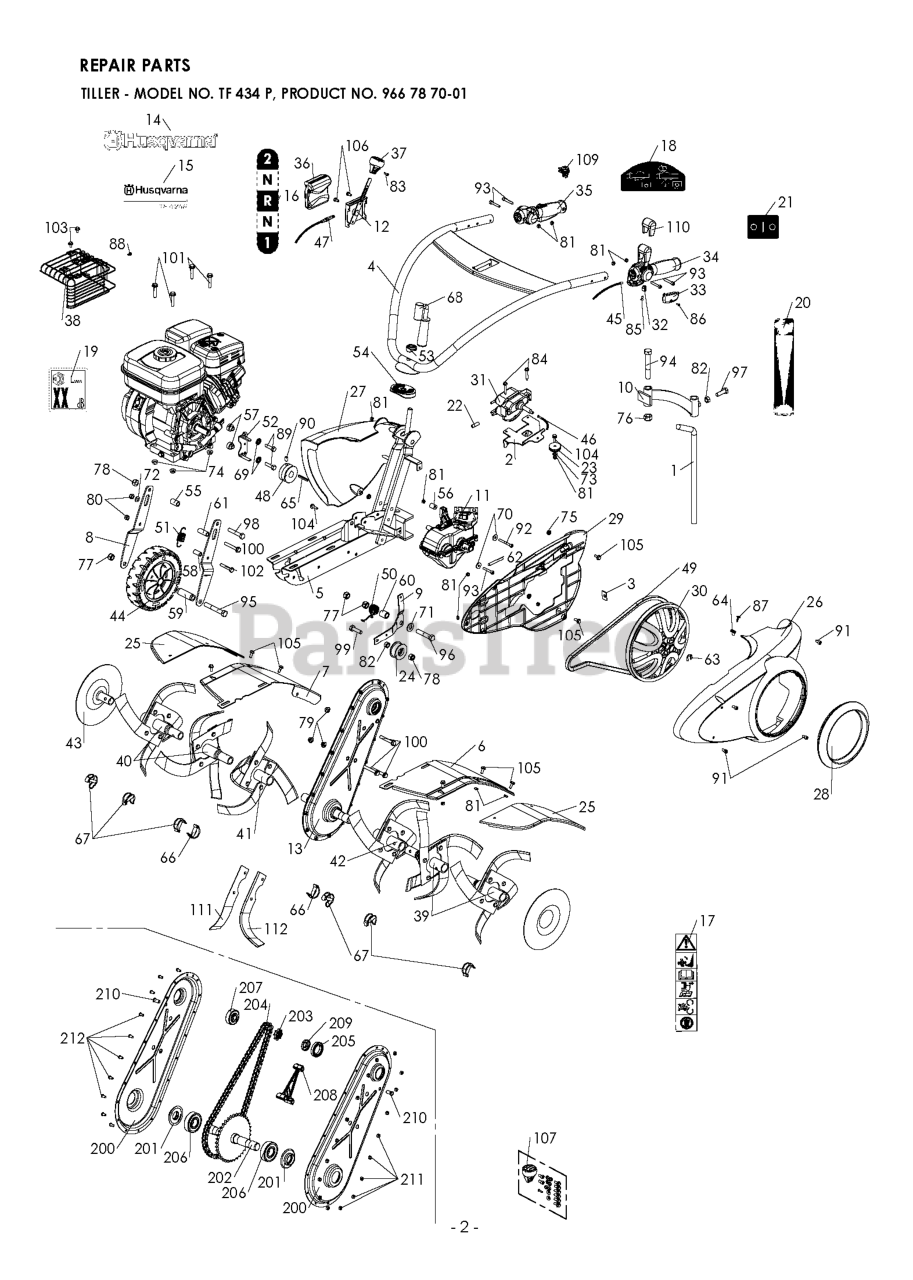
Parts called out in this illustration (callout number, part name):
45	REPL BY 519 00 64-26
63	RETAINER RING
81	Blocking nut M 6 Z
205	BALL BEARING
211	Blocking nut M 6 Z
